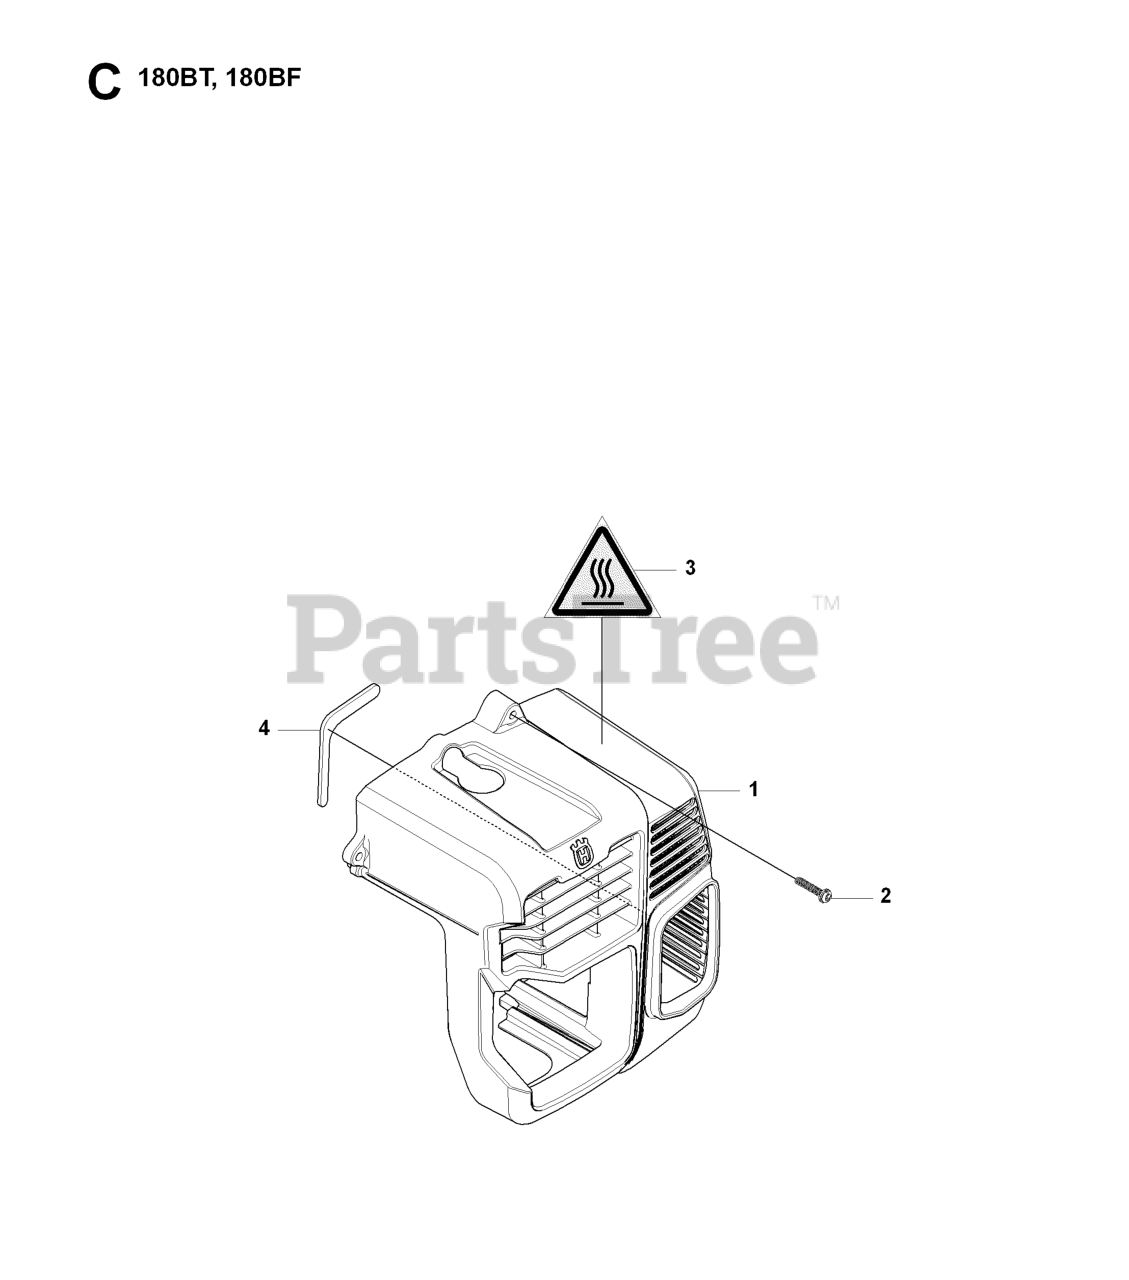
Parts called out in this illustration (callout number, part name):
1	ENGINE COVER
2	SCREW
3	RP_LABEL, HOTMARK
